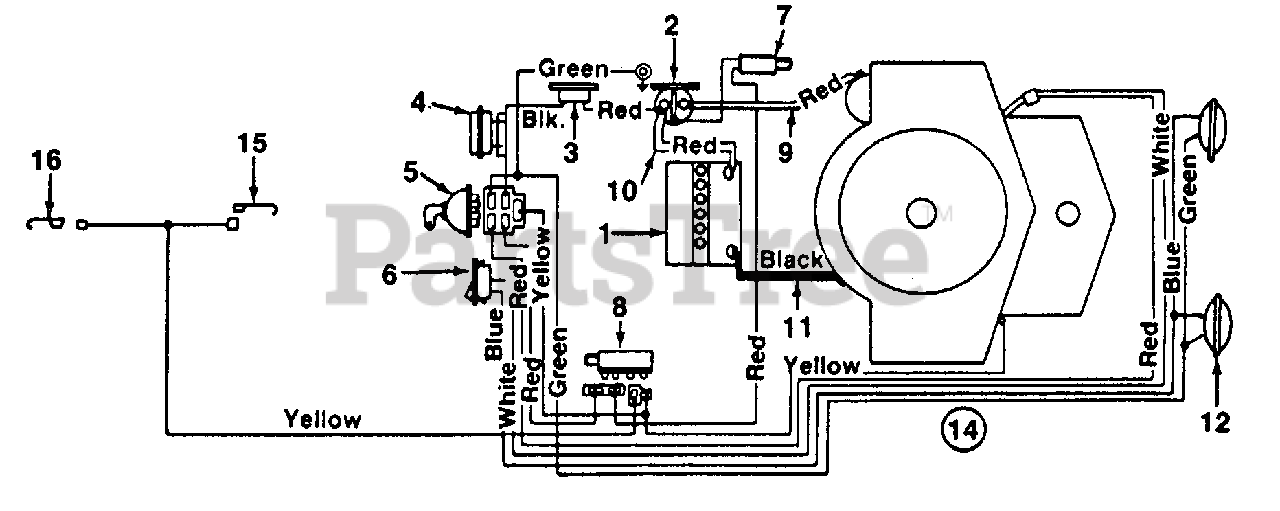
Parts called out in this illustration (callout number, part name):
1	Battery
2	Solenoid
3	Circuit Breaker
4	Ammeter
5	Ignition Switch
6	Light Switch
7	Safety Switch
8	Safety Switch
9	Electric Wire 14" Lg.
10	Electric Wire 7.5" Lg.
11	Ground Wire 7.5" Lg.
12	Lamp
14	Wire Harness
15	Spring Switch
16	Spring Switch
